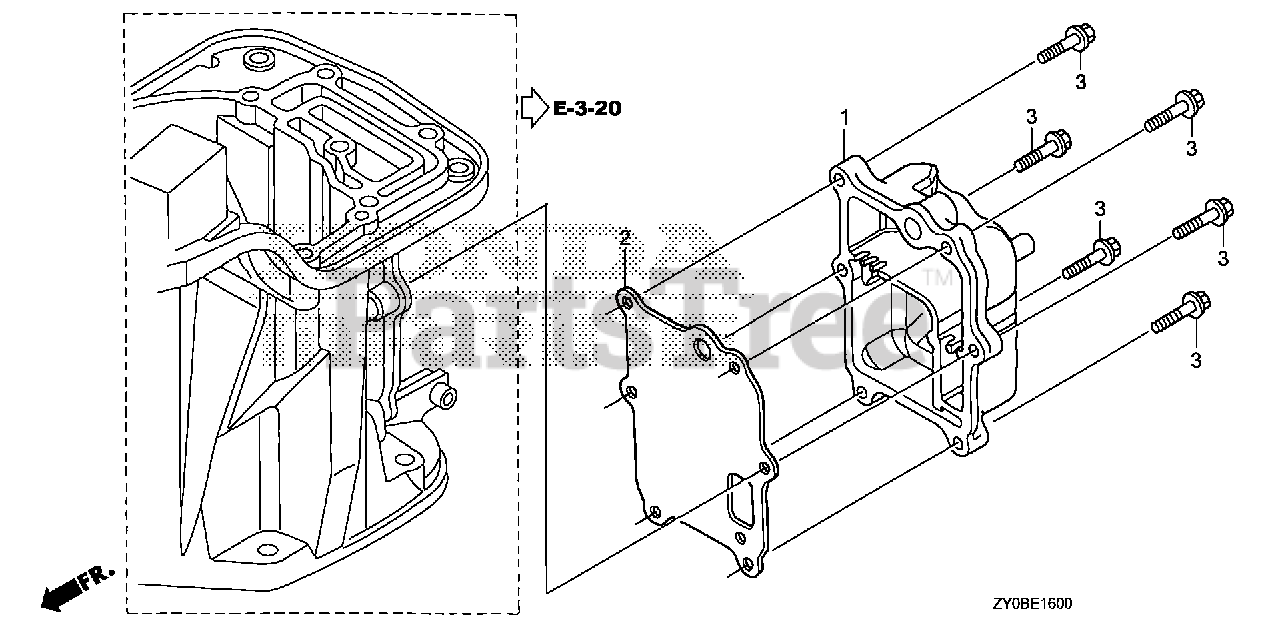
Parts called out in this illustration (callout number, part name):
1	COVER, EX. CHAMBER
2	GASKET, EX. CHAMBER
3	BOLT, FLANGE (6X23) Use from Frame SN 4800343.
